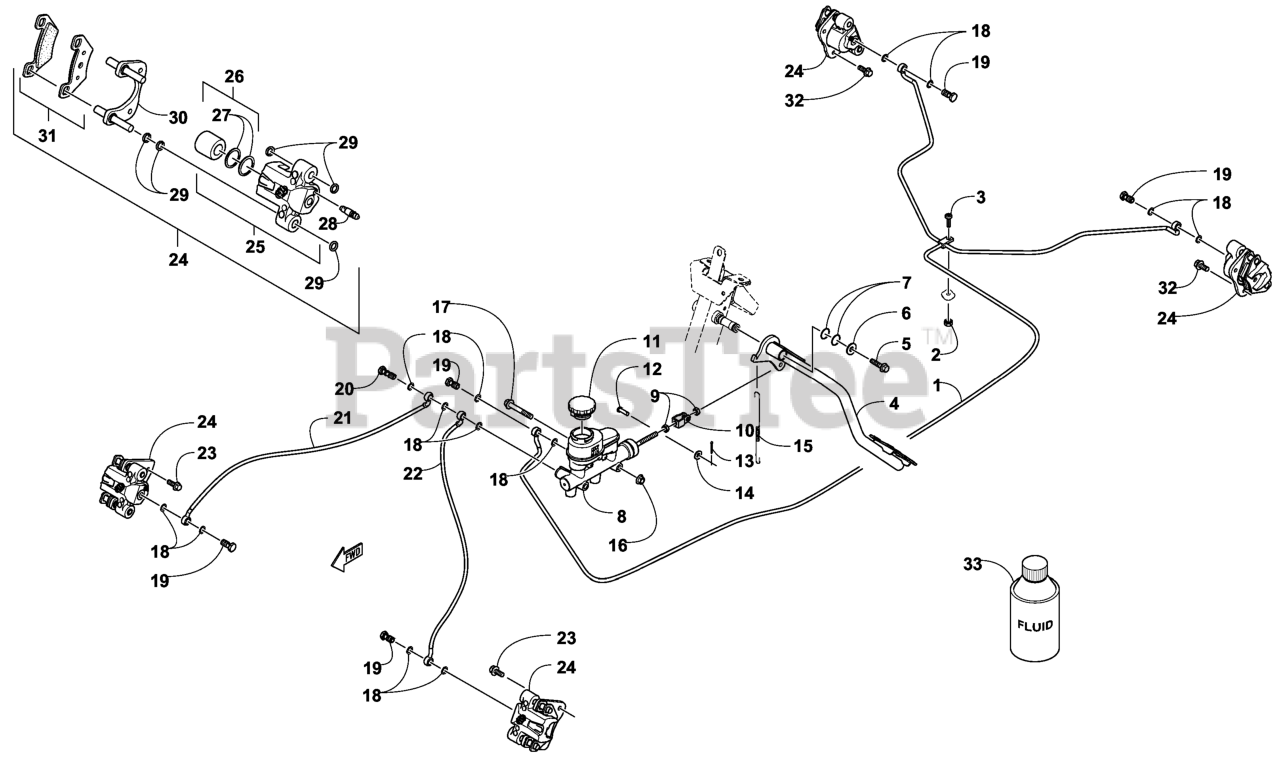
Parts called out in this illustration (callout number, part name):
1	HOSE-BRAKE, REAR
2	NUT-HH, SEMS
3	SCREW-TSPRH
4	PEDAL-BRAKE
5	SCREW-HFH
6	WASHER-FLAT, HARDENED
8	CYLINDER
9	NUT-JAM
11	KIT-SERVICE CAP, TANDEM M
12	PIN-CLEVIS
13	PIN-COTTER
14	WASHER-FLAT
15	SPRING-BRAKE SWITCH
16	NUT-HHF, LOCK, (NI)
17	SCREW-HFH
18	WASHER-CRUSH
19	BOLT-BANJO FITTING
20	BOLT-BANJO FITTING, DOUBL
21	HOSE-BRAKE, FRONT RH
22	HOSE-BRAKE, FRONT
23	SCREW-HFH
24	KIT-CALIPER, FULL ASM (RH
24	KIT-CALIPER, FULL ASM (LH
25	KIT-HOUSING (PISTONS, SEA
27	SEAL SET
28	BLEEDER-CALIPER
30	ARM - IDLER
30	BRACKET ASM
31	KIT-BRAKE PAD (SET)
32	SCREW-HFH
33	DOT 4 BRAKE FLUID - 12 OZ
